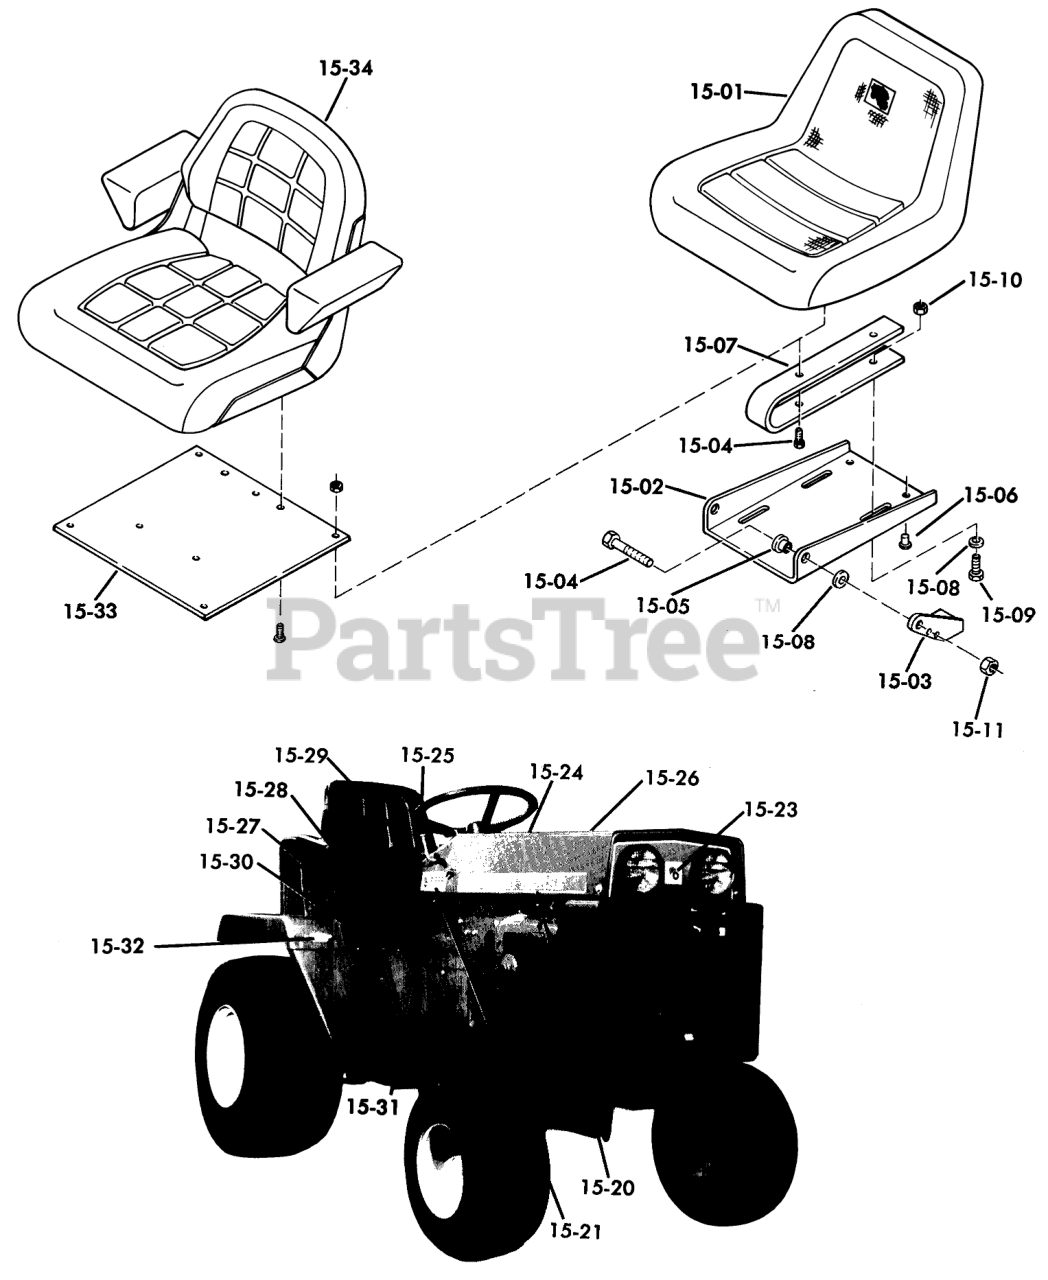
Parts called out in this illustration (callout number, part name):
15-01	Seat
15-02	Plate Seat Pivot
15-03	Bracket-Pivot RH
15-04	Bolt
15-05	BUSHING
15-06	BUMPER-RUBBER
15-07	Seat Spring
15-08	WASHER 5/16 SAE
15-09	HHCS
15-10	Nut
15-11	Nut
15-20	Decal
15-21	Decal-"D-160 Automatic"
15-21	Decal-"D-200 Automatic"
15-22	Decal-Tach-a-matic
15-23	Decal
15-24	Decal-Clutch Knob
15-25	Sleeve
15-26	Decal
15-28	Decal-Caution
15-29	Decal
15-30	Decal-Maintenance
15-31	Decal-Parking Brake
15-32	Reflector
15-33	Seat Plate
15-34	Seat
